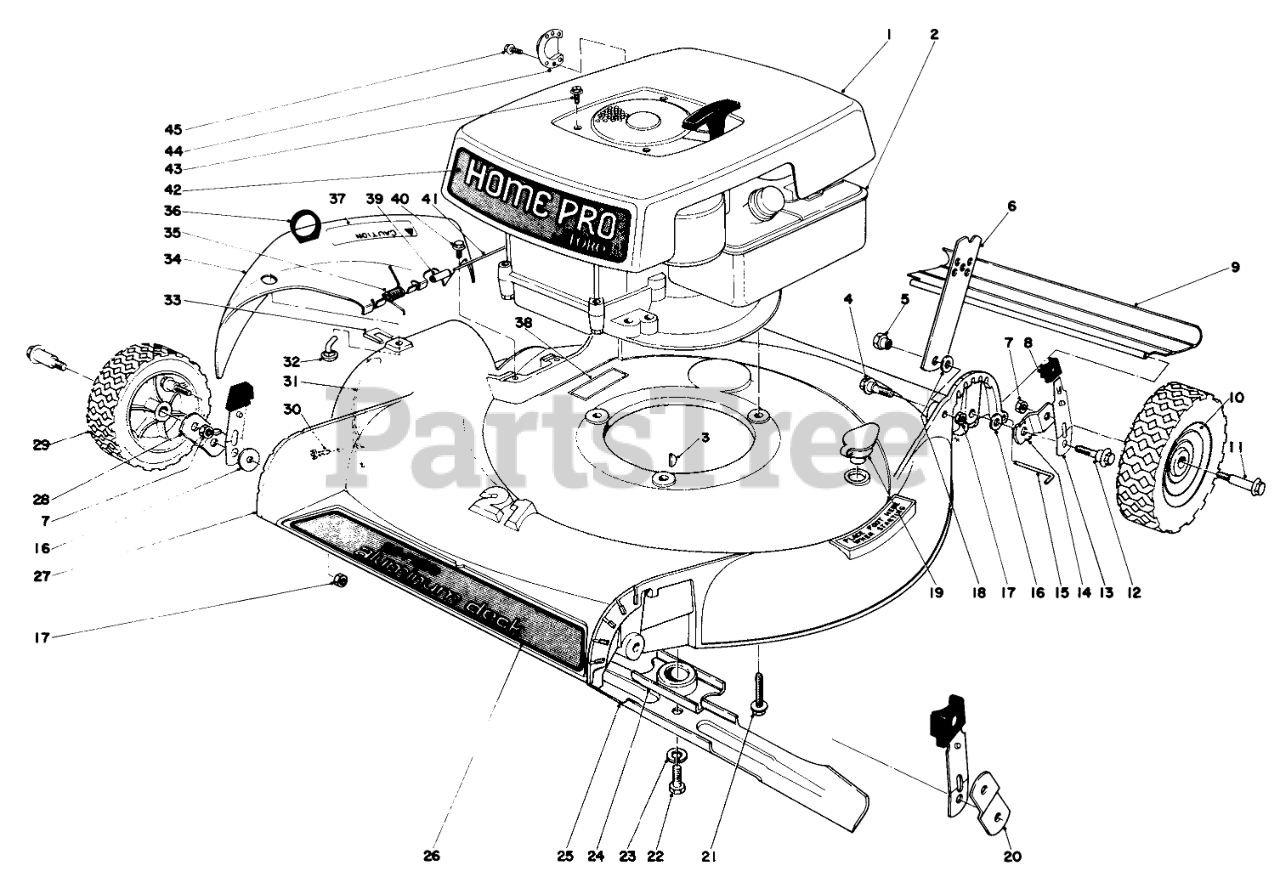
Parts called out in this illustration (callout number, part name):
1	Shroud
1	Throttle Control
2	Engine
3	KEY-WOODRUFF
3	UPPER HANDLE
4	SCREW-SHOULDER
4	Decal
5	HANDLE PIVOT NUT
5	HANDLE SCREW
6	HANDLE LATCH
6	Lower Handle
7	Nut
8	KNOB-ARM
9	SHIELD - TRAILING
10	WHEEL ASM 8
12	PIVOT SCREW
13	SPRING ARM ASM
14	PIVOT ARM PLATED
15	SHIELD ROD
16	WASHER-PIVOT
17	Nut
18	HANDLE LATCH SPACER
19	WASHOUT PLUG
20	PIVOT ARM C PLTD
21	SCREW-HWHTF
22	SPECIAL SCREW
23	WASHER-LOCK
24	Blade Retailer
25	Blade
26	Decal-Deck
27	Housing (Incl. Ref. #26 & 38)
28	PIVOT ARM D PLTD
29	WHEEL ASM 7
30	Screw Thread Forming
31	Bar Safety
32	BAG CHUTE PIN
33	BAG CHUTE CLIP PIN
34	Deflector
35	TORSION SPRING
36	LIFT LOOP
37	Caution Decal
38	Decal Warning
39	SLEEVE
40	SCREW
41	HINGE PIN
42	Decal Shroud
43	8X1/2 SELF TAP SCREW
44	Deflector
45	SCREW W/ENGINE
